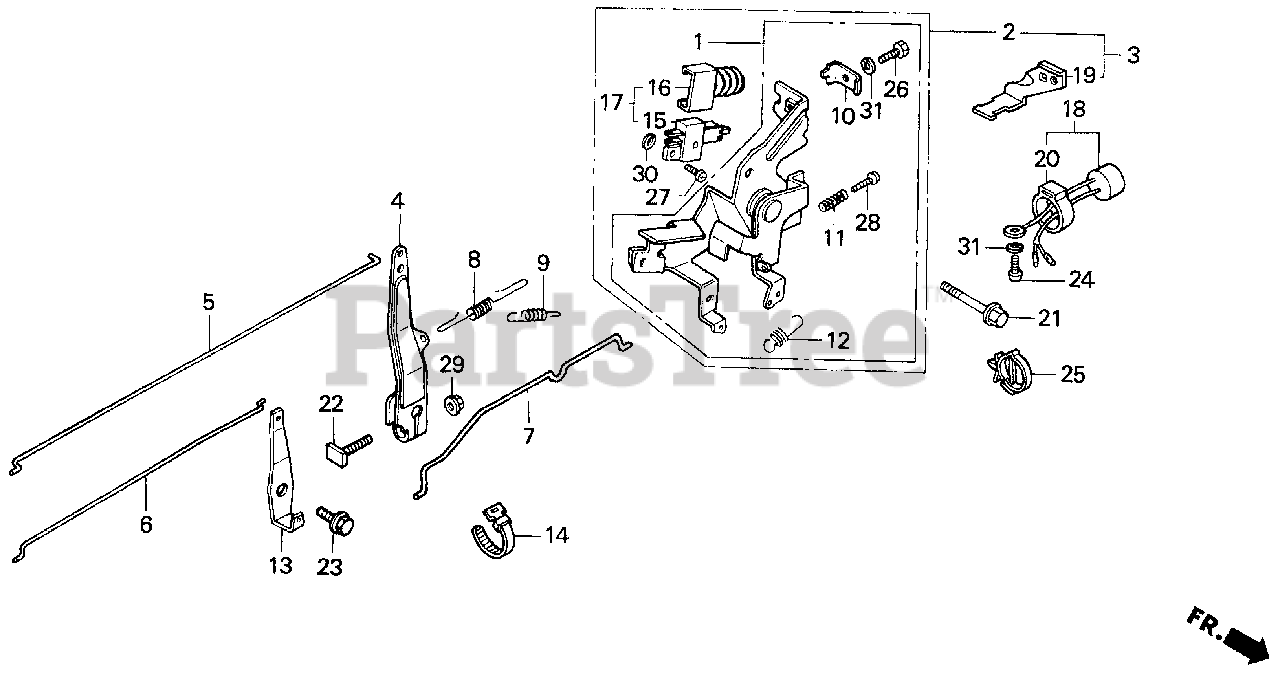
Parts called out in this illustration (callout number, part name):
2	CONTROL ASSY.
4	ARM, GOVERNOR
5	ROD, GOVERNOR
6	ROD, CHOKE
7	ROD, JOINT
8	SPRING, GOVERNOR
9	SPRING, GOVERNOR PRIMARY
10	HOLDER, CABLE
11	SPRING, CONTROL ADJUSTING
12	SPRING, CABLE RETURN
13	LEVER, CHOKE JOINT
14	BAND B1, CABLE
15	SWITCH ASSY., ENGINE
16	COVER, SWITCH
17	SWITCH ASSY., ENGINE STOP
21	BOLT, FLANGE (6X12) (CT200)
22	BOLT, GOVERNOR ARM
23	BOLT, FLANGE (6MM)
26	BOLT, RECESSED (5X14)
26	BOLT, RECESSED (5X16)
27	SCREW, PAN (4X14)
28	SCREW, PAN (5X20)
29	NUT, FLANGE (6MM)
30	WASHER, SPRING (4MM)
31	WASHER, SPRING (5MM)
